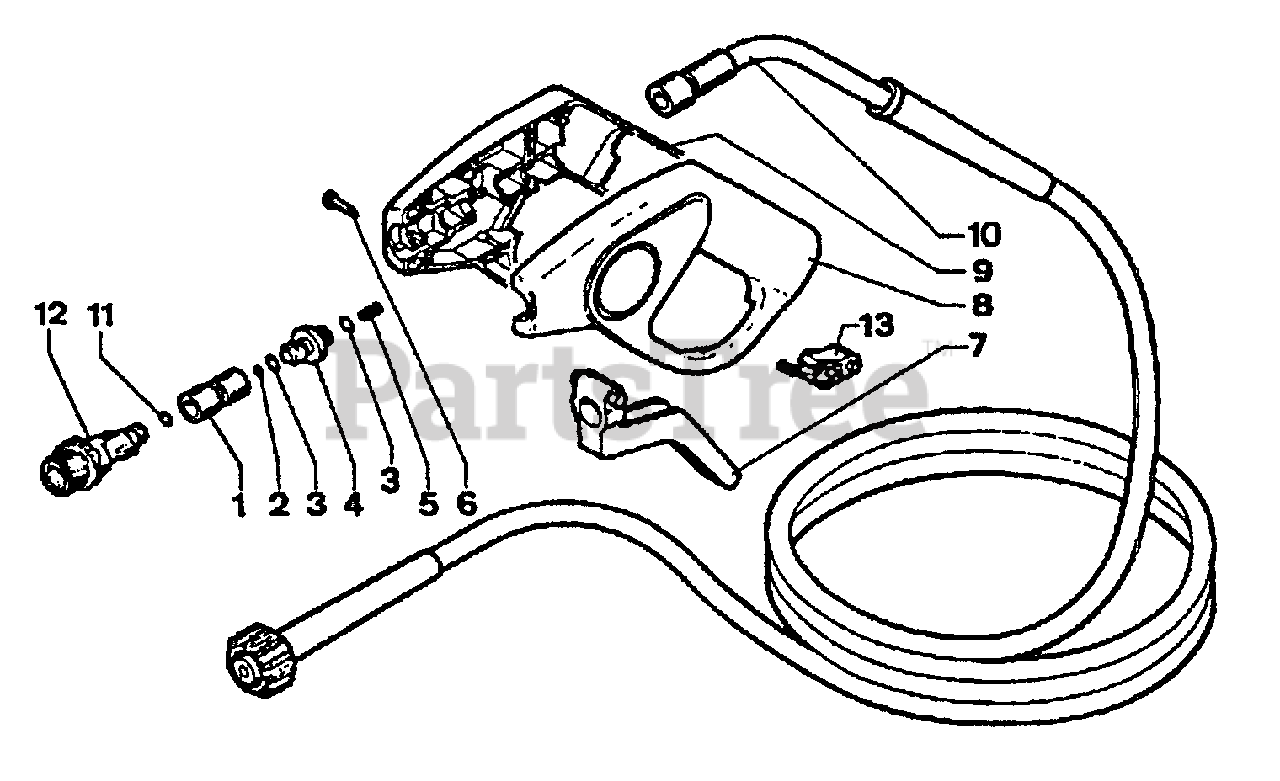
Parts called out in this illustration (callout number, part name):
1	BODY, PISTOL UNLOADER
2	O-RING - .118 X .079
4	SHUTTER
6	SCREW - 3X16
7	TRIGGER
8	HOUSING, LEFT, PLASTIC - BLACK
9	HOUSING, RIGHT, PLASTIC - BLACK
10	HOSE, HIGH PRESSURE, 7MM
11	O-RING - .296 X .084
12	ADAPTOR
13	LATCH - RED
